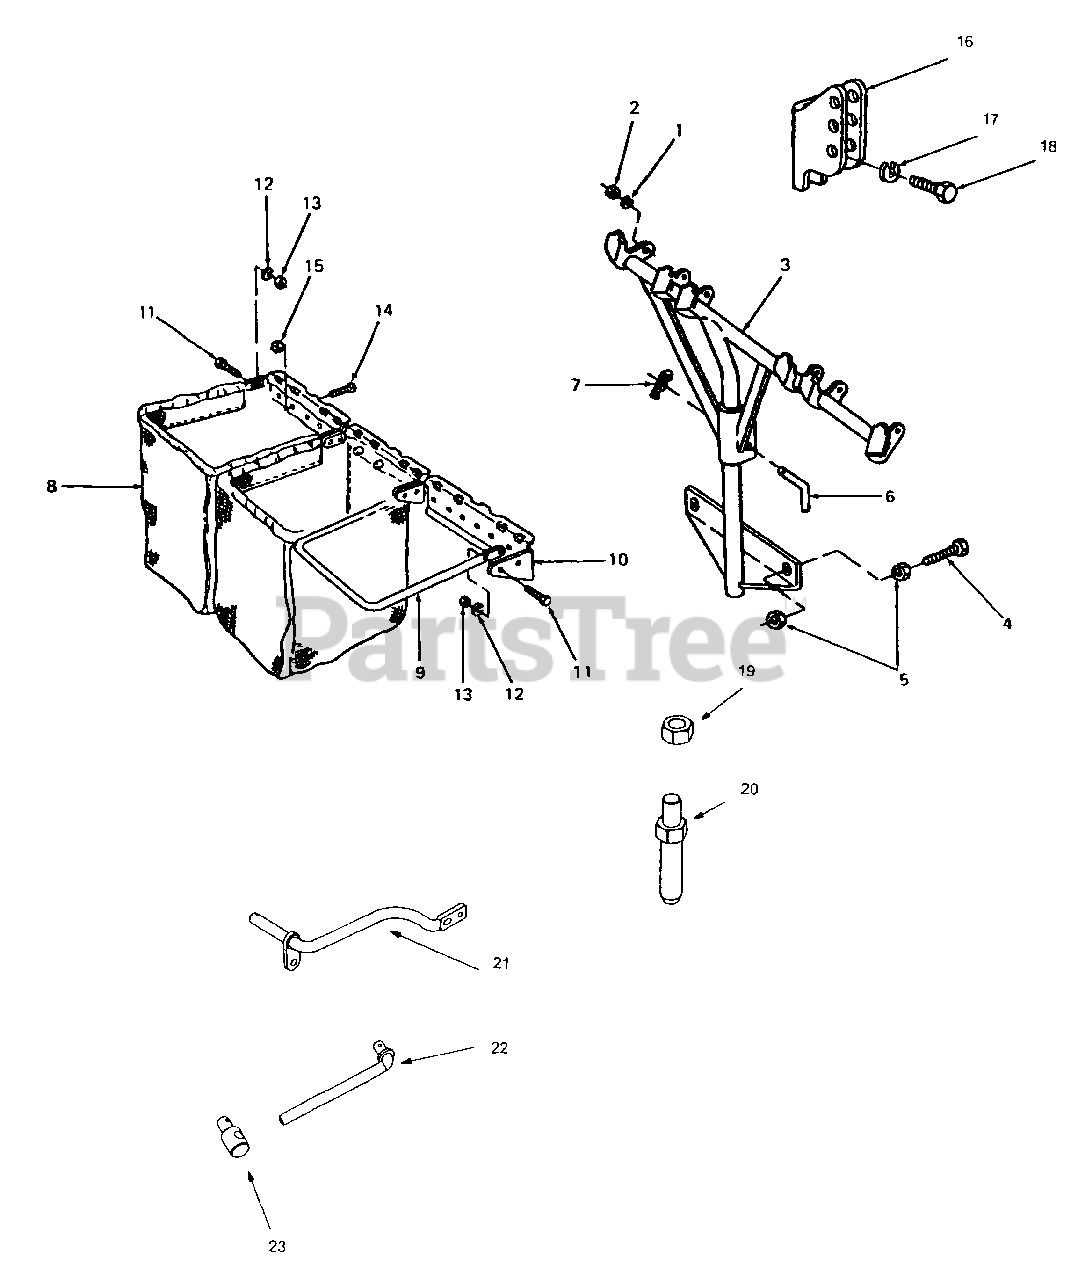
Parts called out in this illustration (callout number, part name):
1	Washer, Lock, 3/8
2	Nut, Hex, 3/8-16
3	Tube Assy, Catcher Support
4	Screw, Hex Cap, 3/8-16 X 1.25 Lg.
5	Nut, Hex Jam, 3/8-16 GR5
6	Pin, Right Angle Clevis
7	Pin, Internal Cotter, 5/8 Dia.
8	Bag, Grass Catcher
9	Frame, Catcher Bag
10	Bracket, Bag Frame Hanger
11	Screw, Hex Cap, 1/4-28 X .75 Lg.
12	Washer, Lock, 1/4
13	Nut, Hex, 1/4-28
14	Screw, Truss Mach, #10-24 X .38 Lg.
15	Nut, Hex Sems, #10-24
16	Hitch Bracket
17	Washer, Lock, 3/8
18	Screw, Hex Cap, 3/8-16 X .88 Lg.
19	Hex Nut, 5/8-18
20	Stud Adapter
21	Reverse Rod Assy.
22	Connecting Rod
23	Adjustment Ferrule
